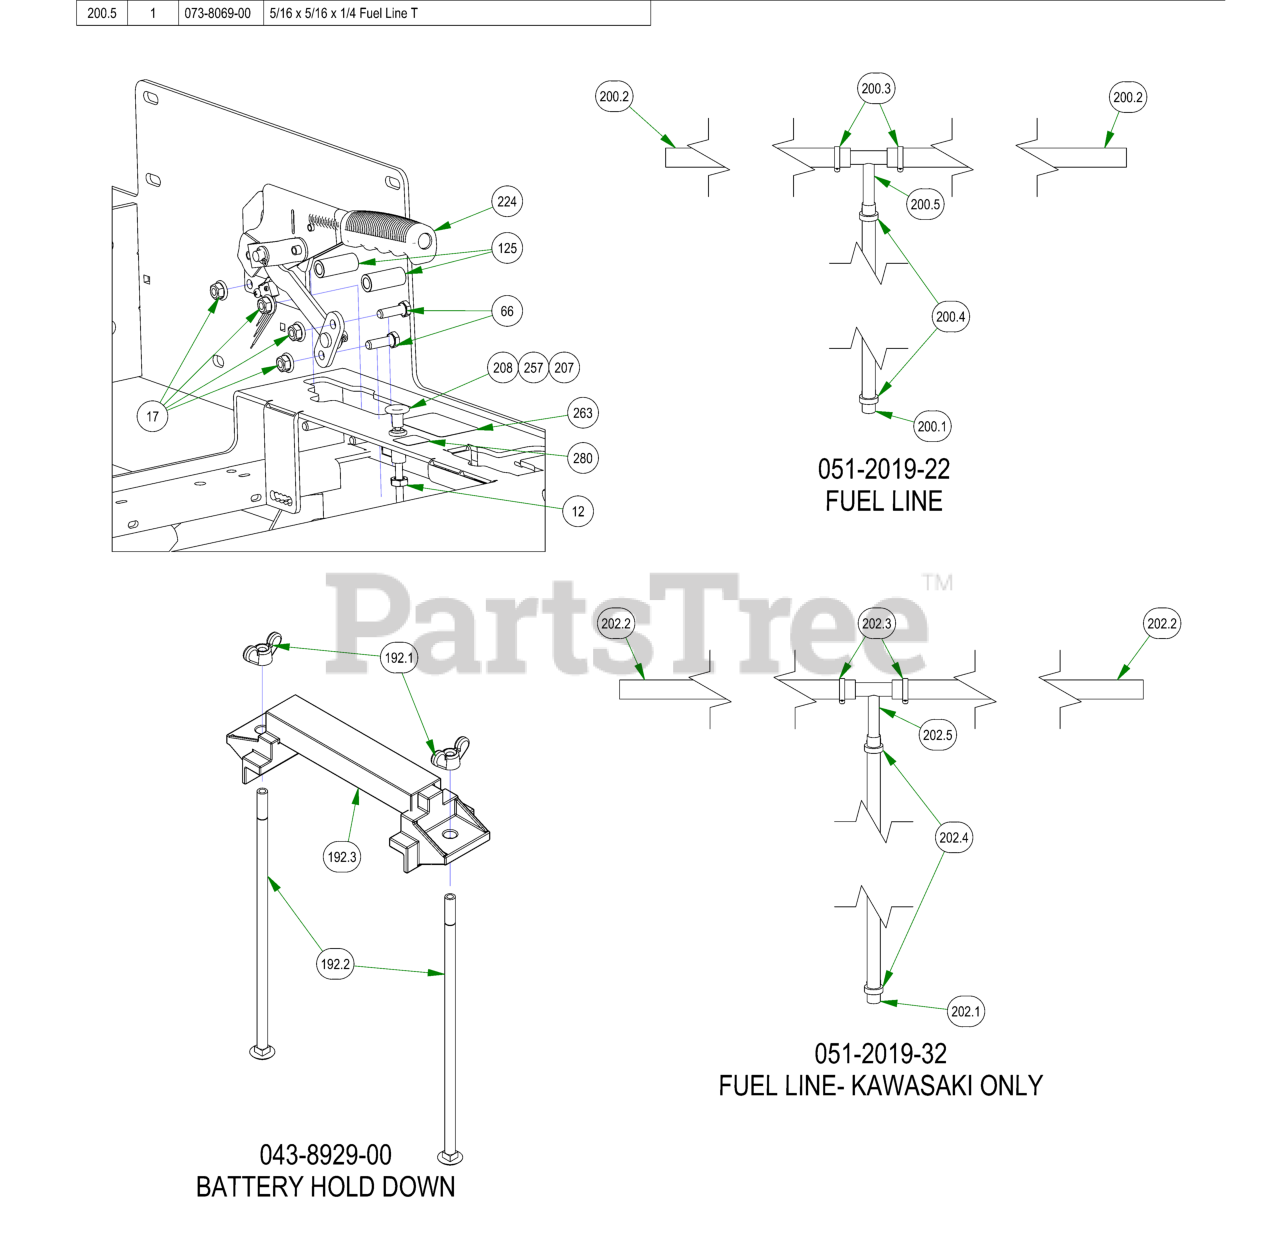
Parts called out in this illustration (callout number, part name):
12	3/8-24 HEX NUT ZINC YELLOW
17	5/16-18 NYLON INSERT FLANGE LOCKNUT ZINC
66	5/16-18 X 1 HEX CAP SCREW (GR.5) ZINC
125	.380 ID X .625 OD X 1.500 LGTH 2019 OUTLAW BRAKE HANDLE
192.1	1/4" Wing Nut
192.2	1/4-20 X 8 Carriage Bolt
192.3	Battery Hold Down
200.1	1/4" Fuel Line Hose
200.2	5/16" fuel line hose
200.3	5/16 Fuel Line Clamp
200.4	1/4 Fuel Hose Clamp
200.5	5/16 x 5/16 x 1/4 Fuel Line T
202.1	1/4" Fuel Line Hose
202.2	5/16" fuel line hose
202.3	5/16 Fuel Line Clamp
202.4	1/4 Fuel Hose Clamp
202.5	5/16 x 5/16 x 1/4 Fuel Line T
207	Choke
208	Choke for 36Hp Vanguard & FX1000 Kawasaki
224	2019 Brake Handle Assembly
257	Code Indicator Light
263	2018 Out/XP/Diesel Brake Decal
280	2019 MIL Decal For Rogue EFI Models
